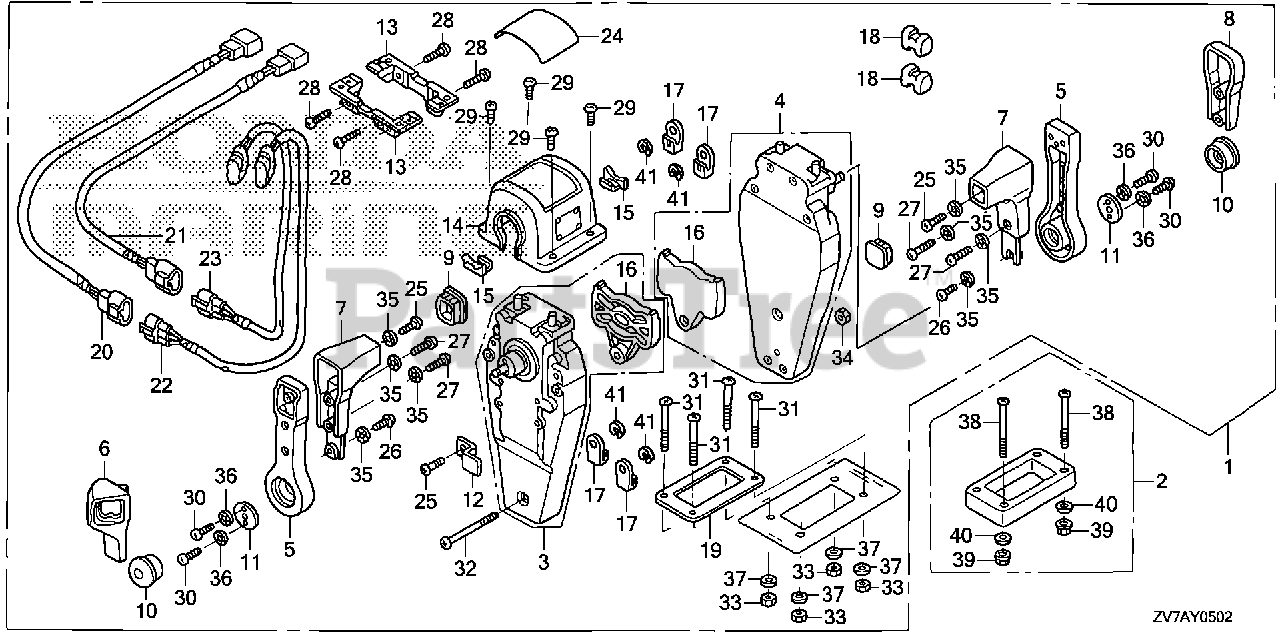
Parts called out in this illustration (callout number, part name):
1	BOX KIT, REMOTE CONTROL (TOP MOUNT DUAL)(R)
2	SPACER KIT, REMOTE CONTROL BOX (TOP MOUNT DUAL)
3	HOUSING ASSY., L. (INNER) (TOP MOUNT)
4	HOUSING ASSY., R. (INNER) (TOP MOUNT)
5	HANDLE, REMOTE CONTROL
6	COVER, L. GRIP
7	GRIP, REMOTE CONTROL HANDLE
8	COVER, DUAL GRIP
9	CAP, GRIP
10	BUTTON, THROTTLE
11	PLATE, HANDLE
12	PLATE, CABLE CLAMP
13	BRACKET, REMOTE CONTROL HOUSING
14	HOUSING, DUAL REMOTE CONTROL BOX
15	HOUSING, LEAD
16	PLATE, DWELL
17	TERMINAL, CABLE
18	SPACER, CABLE CLAMP
19	GASKET, DUAL
20	SUB-HARNESS ASSY., POWER TRIM-TILT (A)
21	SUB-HARNESS ASSY., POWER TRIM-TILT (B)
22	SWITCH ASSY., POWER TRIM-TILT (A)
23	SWITCH ASSY., POWER TRIM-TILT (B)
24	MARK, REMOTE CONTROL (DUAL)
25	SCREW, PAN (5X16)
26	SCREW, PAN (5X10)
27	SCREW, PAN (5X20)
28	SCREW, PAN (5X18)
29	SCREW, PAN (4X10)
30	SCREW, PAN (6X18)
31	SCREW, PAN (5X40)
32	SCREW, PAN (5X55)
33	NUT, HEX. (5MM)
34	NUT, HEX. (5MM)
35	WASHER, LOCK (5MM)
36	WASHER, LOCK (6MM)
37	WASHER, PLAIN (5MM)
38	SCREW, PAN (5X65)
39	NUT, HEX. (5MM)
40	WASHER, PLAIN (5MM)
41	E-RING (6MM)
